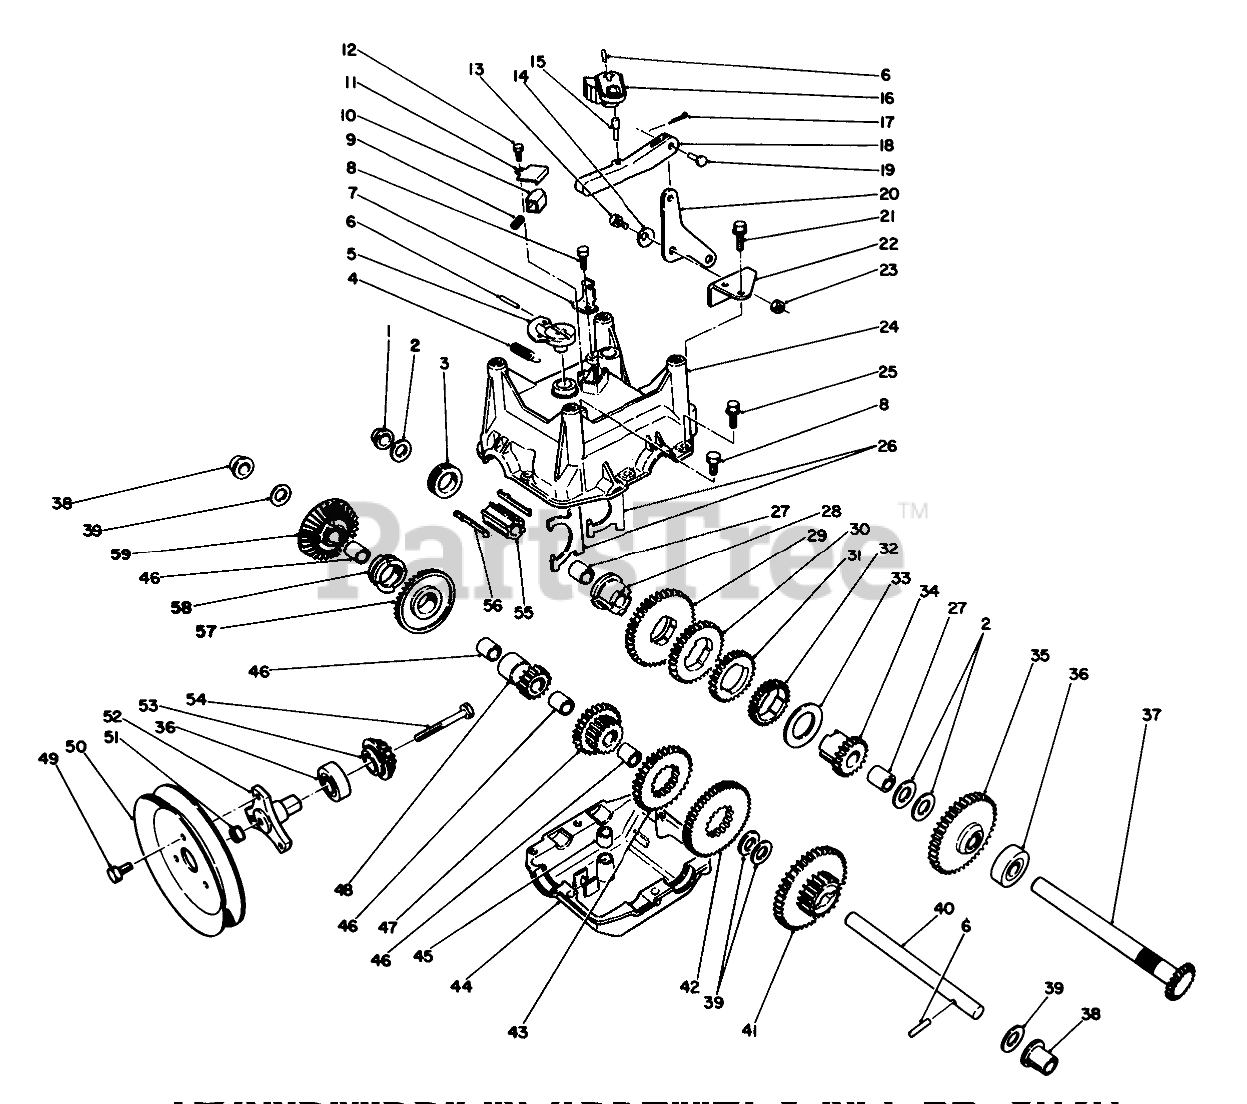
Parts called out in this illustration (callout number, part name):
1	BUSHING-FLANGE, OUTPUT
2	BEARING-THRUST
3	COLLAR-SHIFT
4	SPRING-EXTENSION
5	LEVER
6	PIN-SPRING
7	BRACKET-CABLE
8	SCREW-HWH
9	SPRING-DETENT
10	BUTTON-DETENT
11	COVER-DETENT
12	SCREW-HWH
13	SCREW-SHOULDER
14	WASHER-CURVED
15	PIN-LINK, GEAR SHIFT
16	LEVER-SHIFT, GEAR
17	PIN-COTTER
18	LINK-SHIFT, GEAR
19	PIN-CLEVIS
20	BELLCRANK
21	SCREW-HWH
22	BRACKET-BELLCRANK
23	NUT-LOCK, NI
24	GEARCASE-UPPER, CASING
25	SCREW-HWHTF
26	YOKE-SHIFT
27	BUSHING-OUTPUT
28	SLEEVE-GEAR
29	GEAR-45 T
30	GEAR-34 T
31	GEAR-27 T
32	GEAR-29 T
33	WASHER-THRUST
34	GEAR-SLEEVE, 19 T
35	GEAR-41 T
36	BEARING-BALL
37	SHAFT-OUTPUT
38	BUSHING-INTERMEDIATE
39	WASHER-THRUST
40	SHAFT-INTERMEDIATE
41	GEAR-19/41 T
42	GEAR-51 T
43	GEAR-33 T
44	GEARCASE-LOWER, CASING
45	BUSHING-YOKE
46	Bushing-Output
47	GEAR-26 T
48	GEAR-BEVEL, 15 T
49	SCREW
50	TRACTION-SHEAVE, HALF
51	NUT-HHF
52	HUB-PULLEY
53	PINION-BEVEL
54	SCREW-HH
55	SLEEVE-SHIFT
56	KEY-SHIFT
57	GEAR-BEVEL, 36 T
58	COLLAR-SHIFT
59	Gear-Bevel Reverse 36T (Incl. Ref. #46)
